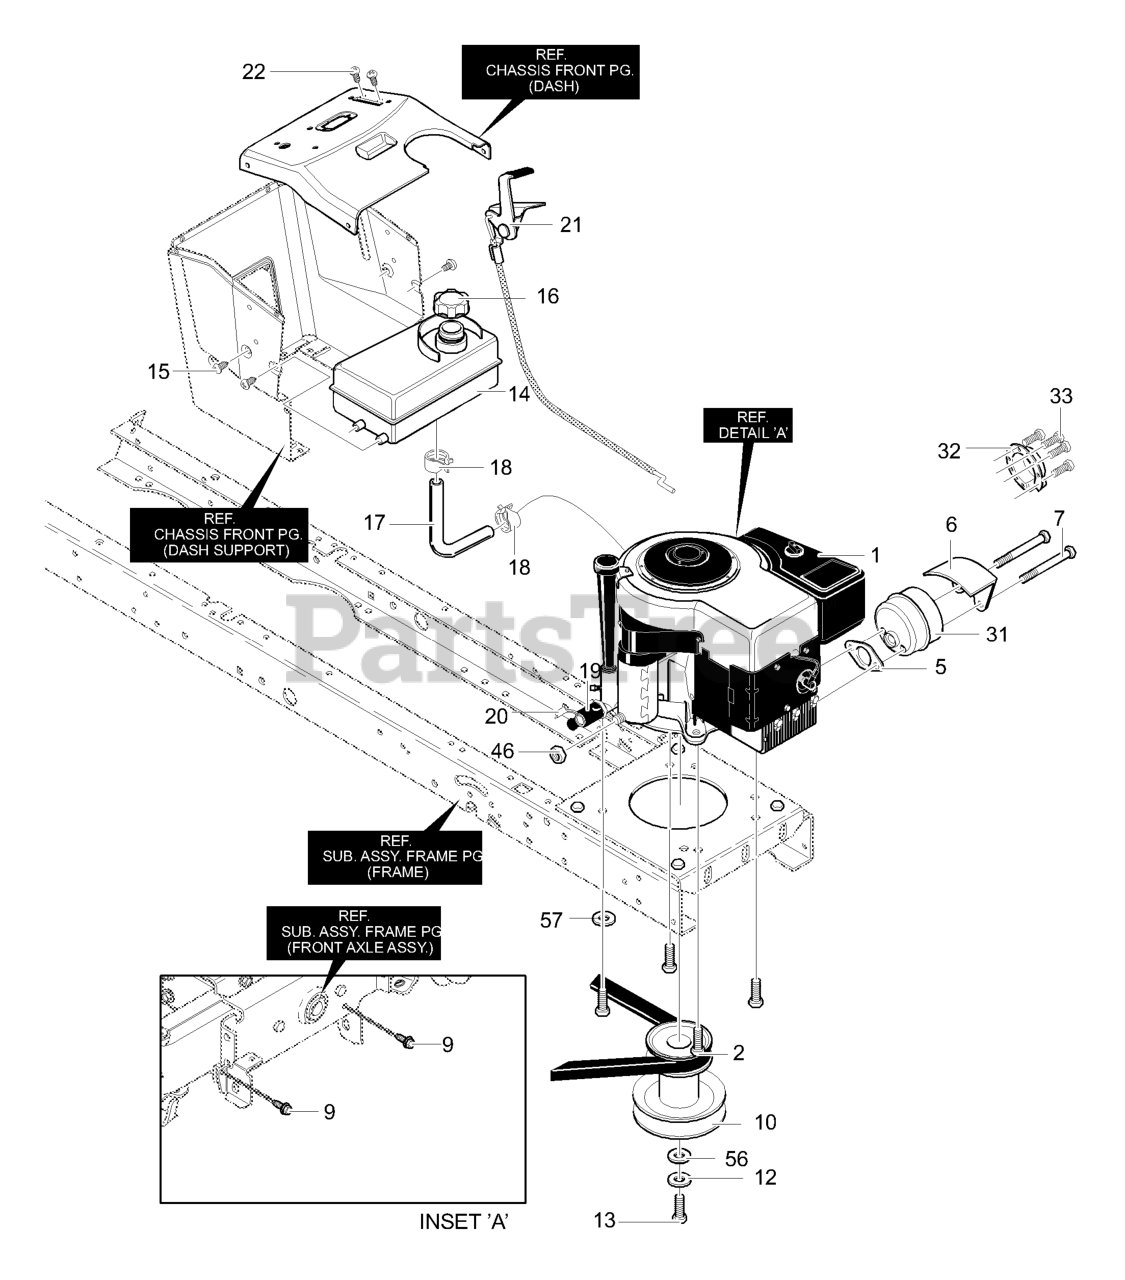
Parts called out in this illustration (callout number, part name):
1	12.5HP Engine
2	Engine Bolt 3/8x1.25
5	GASKET, Exhaust
6	Shield, Heat
7	Screw, 5/16-18 x 4.125
9	Screw, 5/16-18 x 0.75
10	Stack Pulley
12	Washer, Regsptlk
13	Bolt, 7/16-20x1.75LG
14	TANK, Fuel 1.4 Gal.
15	Screw, 15TP
16	Fuel Cap
17	Tubing 14.50 Inches
18	Clamp, Fuel
19	Oil Drain Valve Assembly
20	Cap, Oil Drain Valve
21	Throttle Control
22	Screw, #8-16x.38
31	Muffler
32	Deflector, Exhaust
33	Screw, #8-32x.38
46	Nut, 1/4-20 Reghexjam
56	Washer, Flat
57	Washer, Exlk
